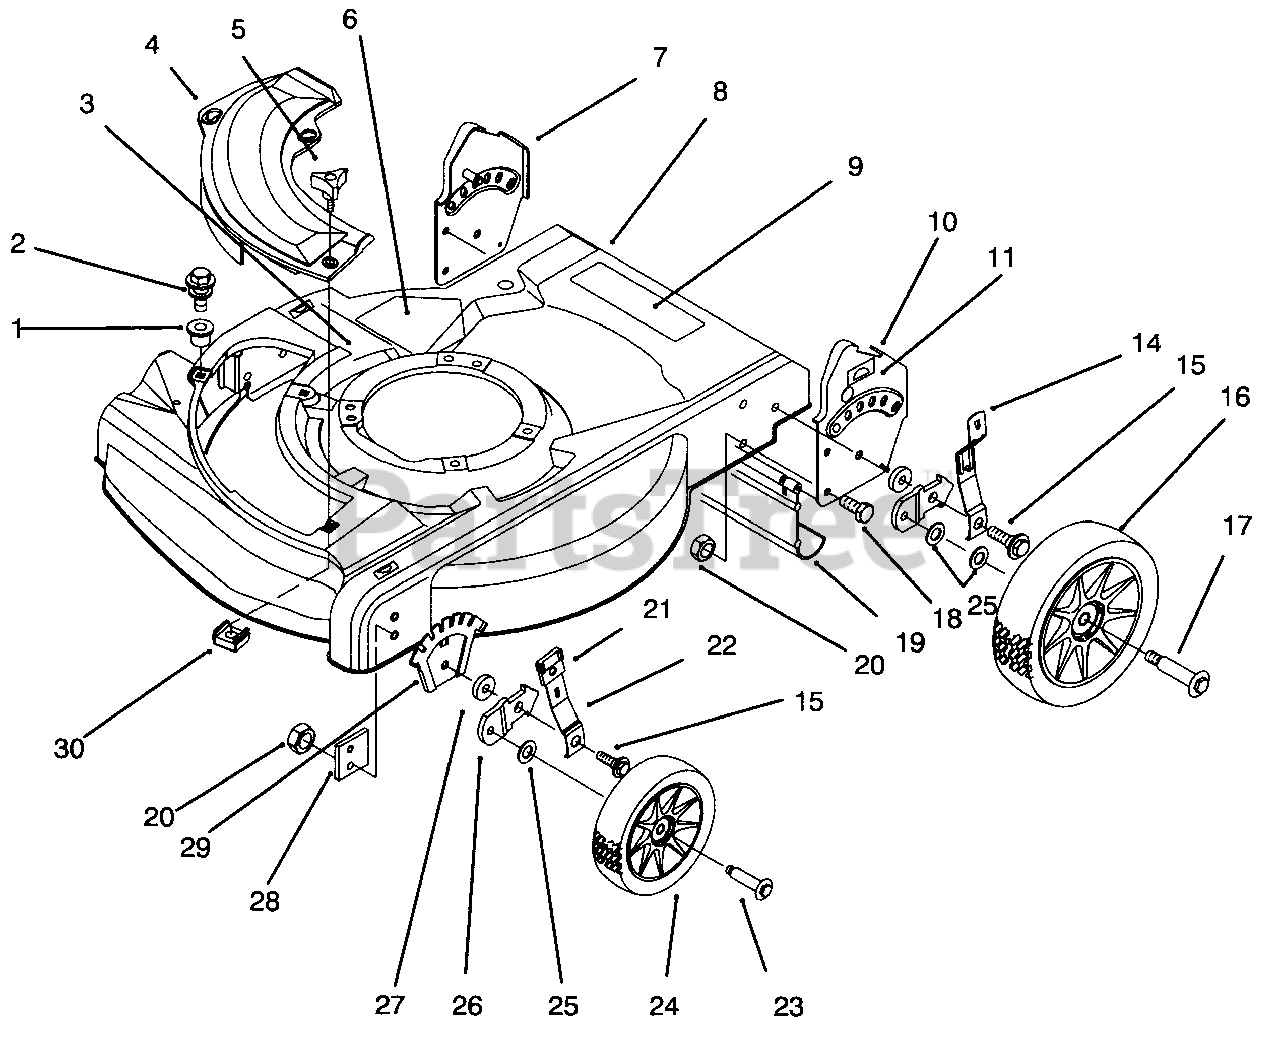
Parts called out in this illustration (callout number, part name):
1	Grommet-Plastic
2	Screw-Thread Forming
3	Decal-Danger
4	Plate-Cover, Mulch
5	Knob
6	Decal-Danger
7	Handle Bracket Ass'y-RH
8	Housing & Baffle Ass'y (Incl. Ref. #1-3, 6, & 9)
9	Decal-Danger
10	Handle Bracket Ass'y-LH
11	Decal-H.O.C. L.H.
14	Spring Arm Assembly
15	Bolt-Shoulder
16	Wheel Ass'y-8"
17	Bolt-Wheel
19	Shield-Trailing
21	Knob-H.O.C. Lever
22	Arm-Spring, Front
23	Bolt-Wheel
24	Wheel Ass'y-6"
25	Washer-Wheel Bolt
26	Bracket-H.O.C.
28	Plate-Baffle
29	Plate-H.O.C. Front
30	Nut-Cage
